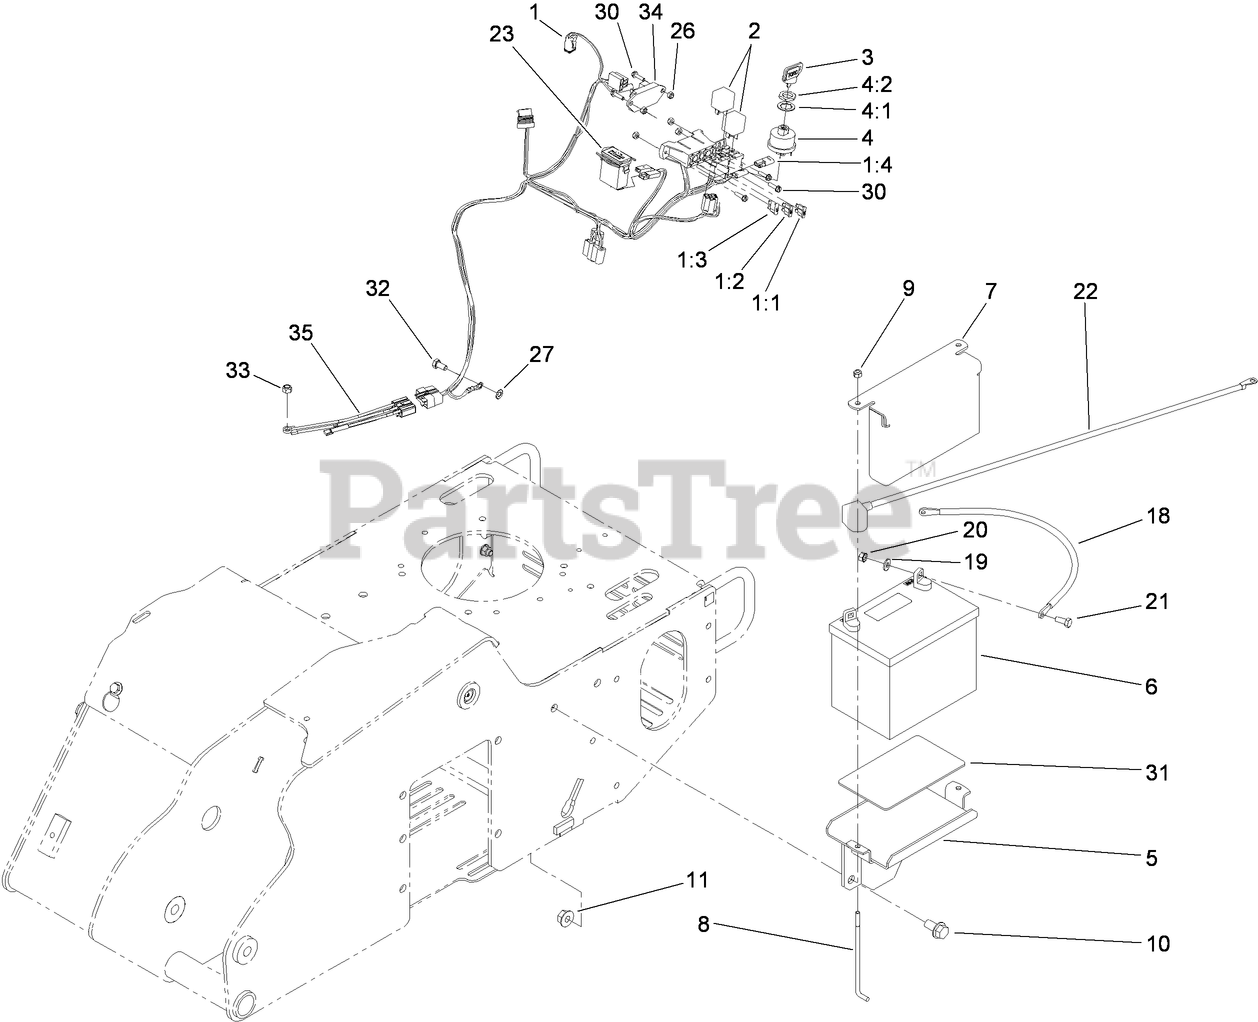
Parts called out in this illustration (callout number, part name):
1	HARNESS-WIRE
1:1	FUSE-BLADE, 30 AMP
1:2	FUSE-BLADE, 25 AMP
1:3	FUSE-BLADE, 20 AMP
1:4	CAP-PLUG
2	RELAY
3	KEY-IGNITION
4	Key Switch ASM
4:1	WASHER-TOOTH, INTERNAL
4:2	NUT-HH
5	TRAY-BATTERY
6	BATTERY-DRY
7	PLATE-HOLD DOWN, BATTERY
8	HOLDOWN-BATTERY
9	NUT-LOCK, NI
10	SCREW-HHF
11	NUT-HHF
18	CABLE-BATTERY, POSITIVE
19	WASHER-FLAT
20	NUT-KEPS
21	SCREW-HH
22	CABLE-BATTERY, BLACK
23	METER-HOUR
26	NUT-LOCK, NI
27	WASHER-LOCK
30	SCREW-HWH
31	PAD-SKID, ANTI
32	SCREW-HH
33	NUT-HF
34	MODULE-DELAY
35	HARNESS
